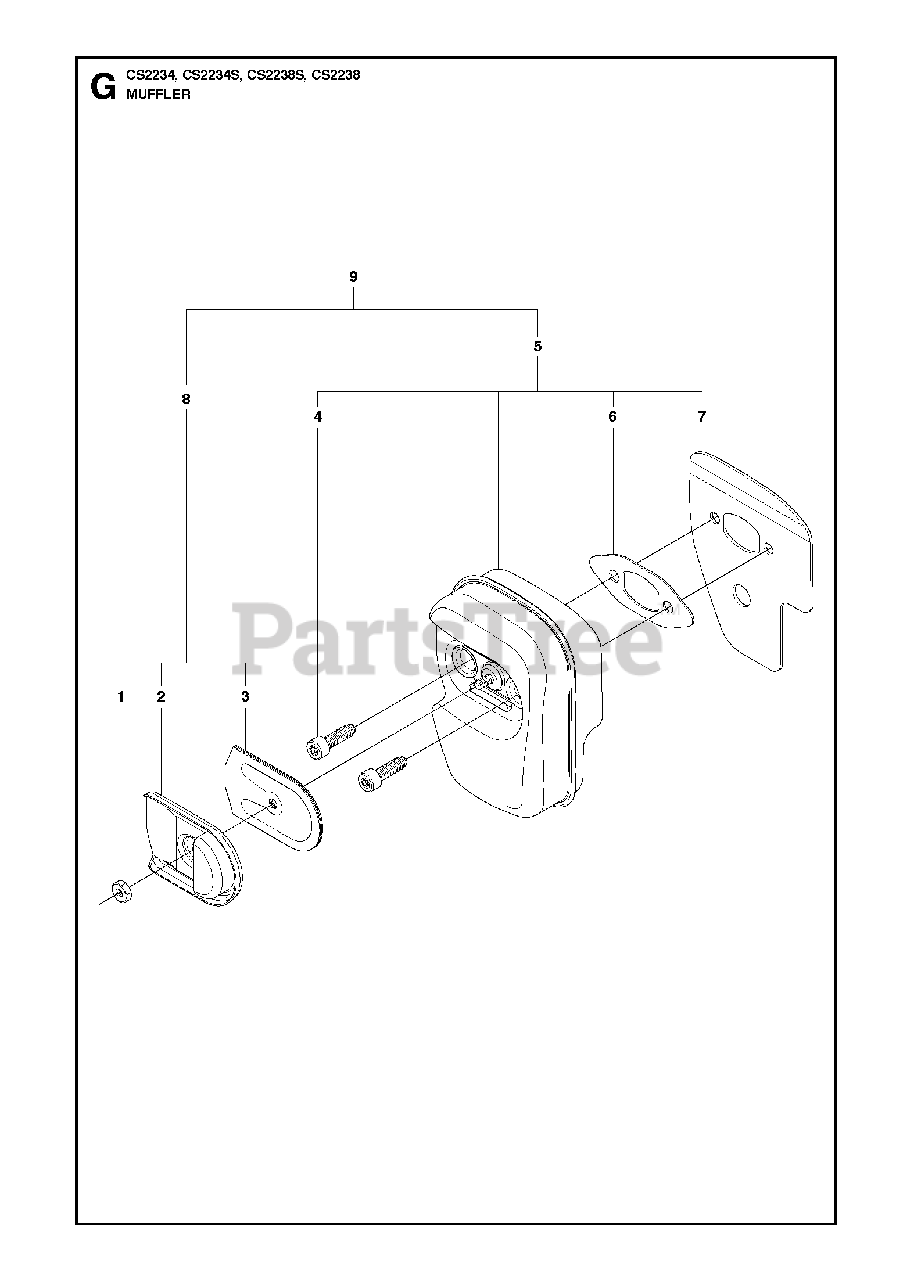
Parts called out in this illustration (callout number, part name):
1	NUT 10MM BRASS
2	EXHAUST PLATE
3	SCREEN ARRESTOR
4	SCREW MUFFLER
5	MUFFLER ASSY
6	GASKET
7	PLATE
8	KIT SPARK ARRESTOR
9	MUFFLER KIT
